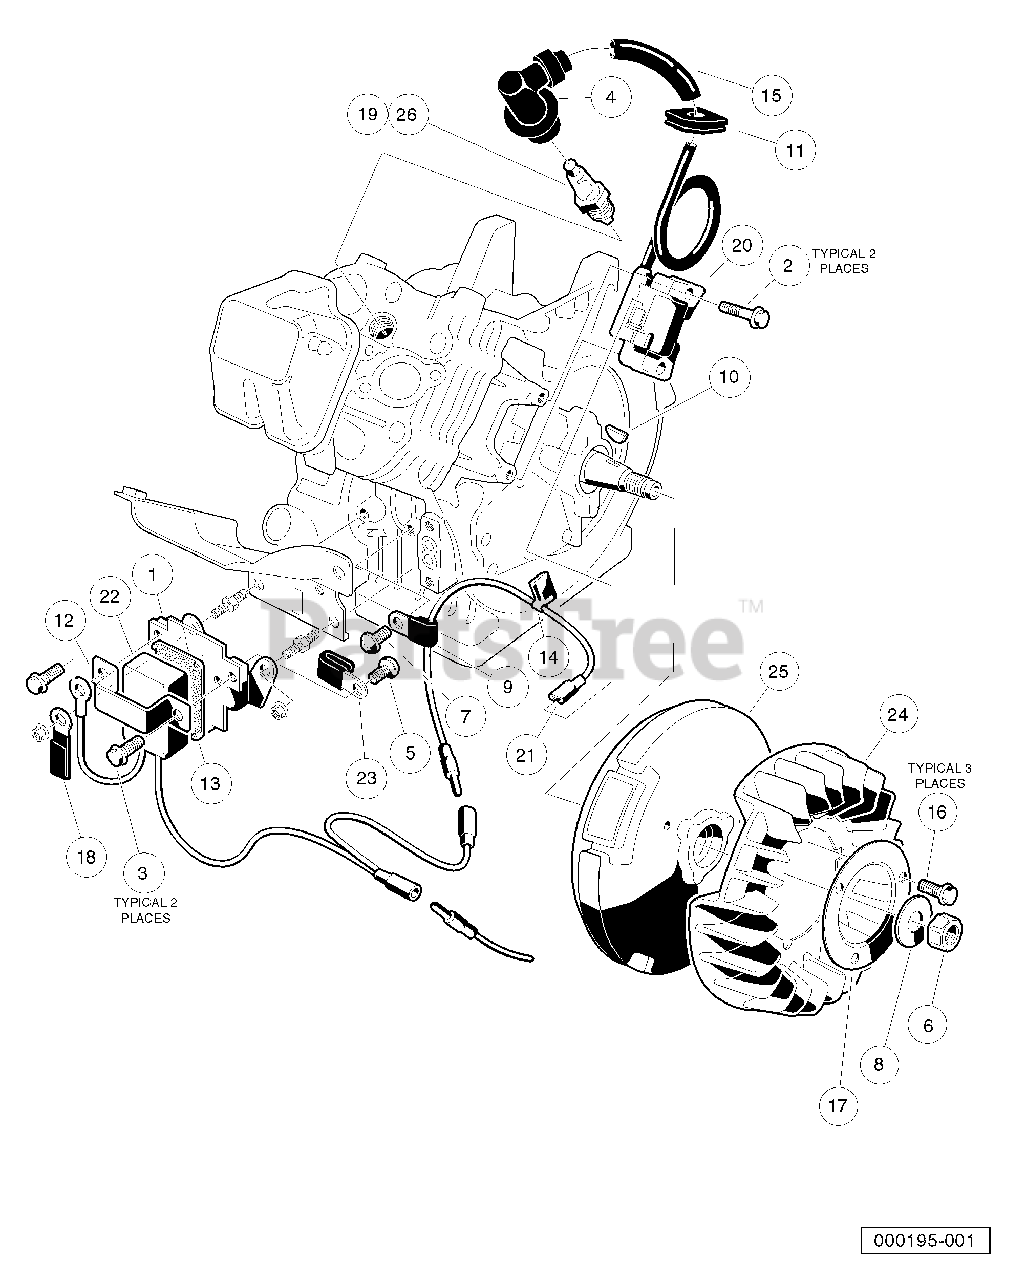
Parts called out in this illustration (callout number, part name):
1	Bracket, RPM Limiter
2	Bolt, Flange Head
3	Bolt, Flange Head, M6 x 1 x 12 mm
4	Cap, Spark Plug
5	Screw, Pan WP Cross
6	Nut, Hex, Fine
8	Washer, M16 Flat
12	Band, RPM Limiter Mount
13	Damper, RPM Limiter
15	Tube, 7mm X 10mm X 70mm
16	Bolt, Flanged
17	Plate, Flywheel Fan
19	Spark Plug, OHV
20	Coil, Ignition
21	Lead Wire Assy
22	Limited RPM
23	Clamp, Steel
24	Fan, FE290
25	Flywheel, Complete
26	Spark Plug, OHV
